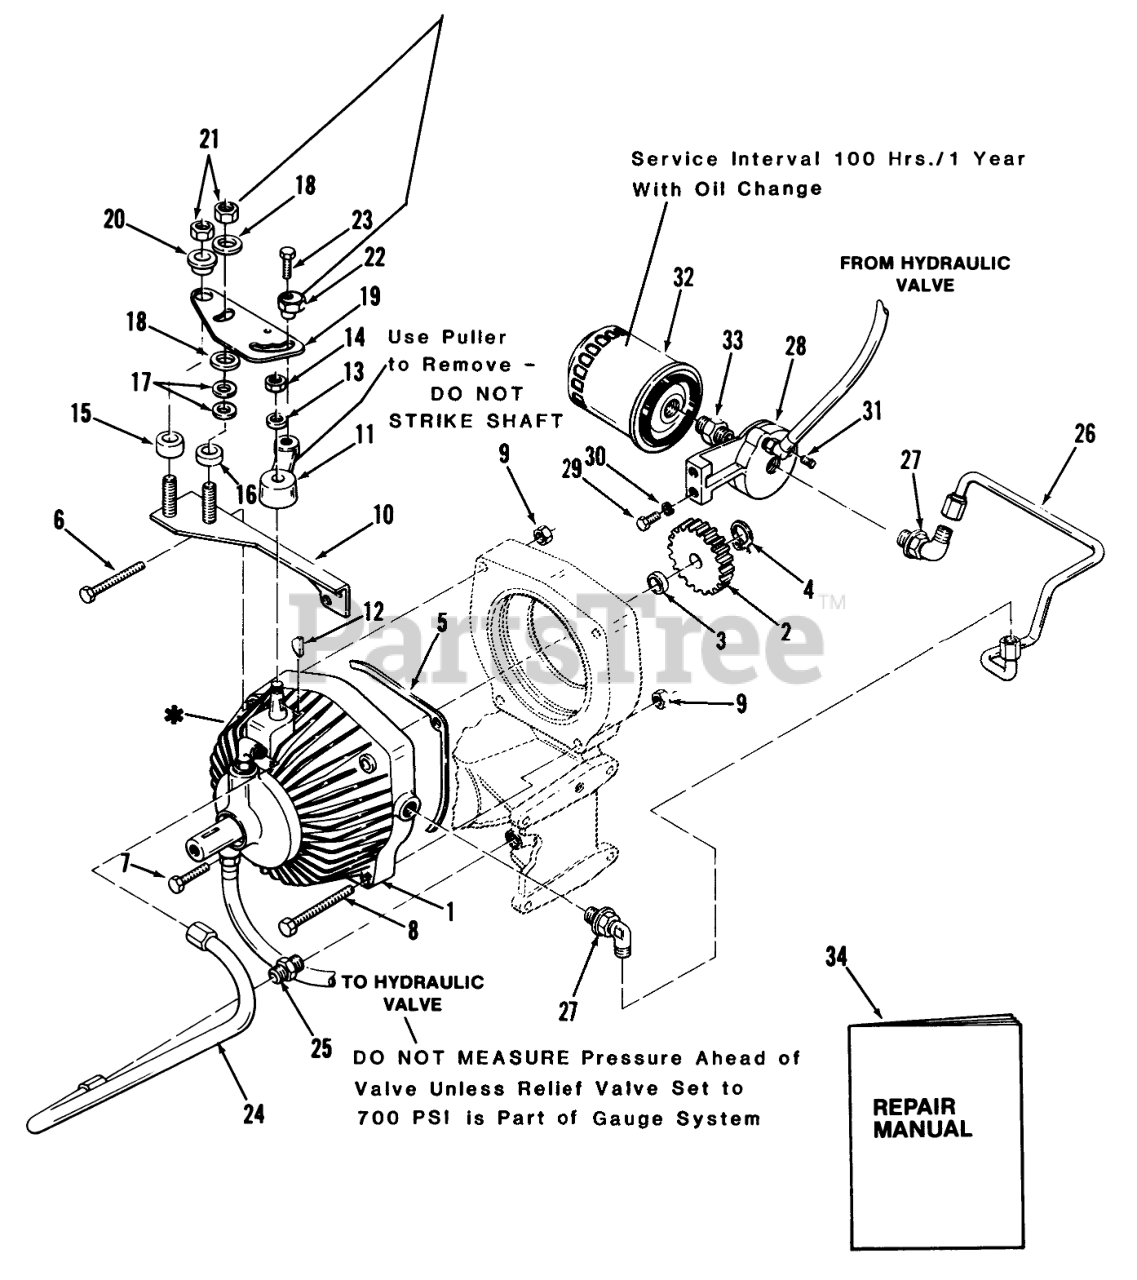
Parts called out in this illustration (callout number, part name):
1	Pump & Motor
2	GEAR 22T DRIVE
3	SPACER GEAR
4	SNAP RING- 5/8 EXT
5	GASKET
6	Hex Bolt
7	Bolt
8	Bolt 3/8-16 x 6 1/2
9	NUT
10	ASSY-PLATE B
11	ARM-SPEED CONTROLB
12	Key #5 Woodruff
13	Washer
14	Nut
15	SPACER-PIVOT
16	SPACER-FRICTION
17	WASHER-SPRING DISC
18	FRICTION WASHER
19	CAM-SPEED CONTROL (NS)
20	CAM-SPACER
23	Bolt
24	ASSY-TUBE SUCTION
25	FITTING-TUBE
26	ASM-TUBE FILTER OUTL
27	ELBOW
28	BASE-FILTER
29	Bolt
30	Lockwasher
31	PLUG 1/4 PIPE ALLEN
32	Filter-Oil
33	FITTING
34	Repair Manual
